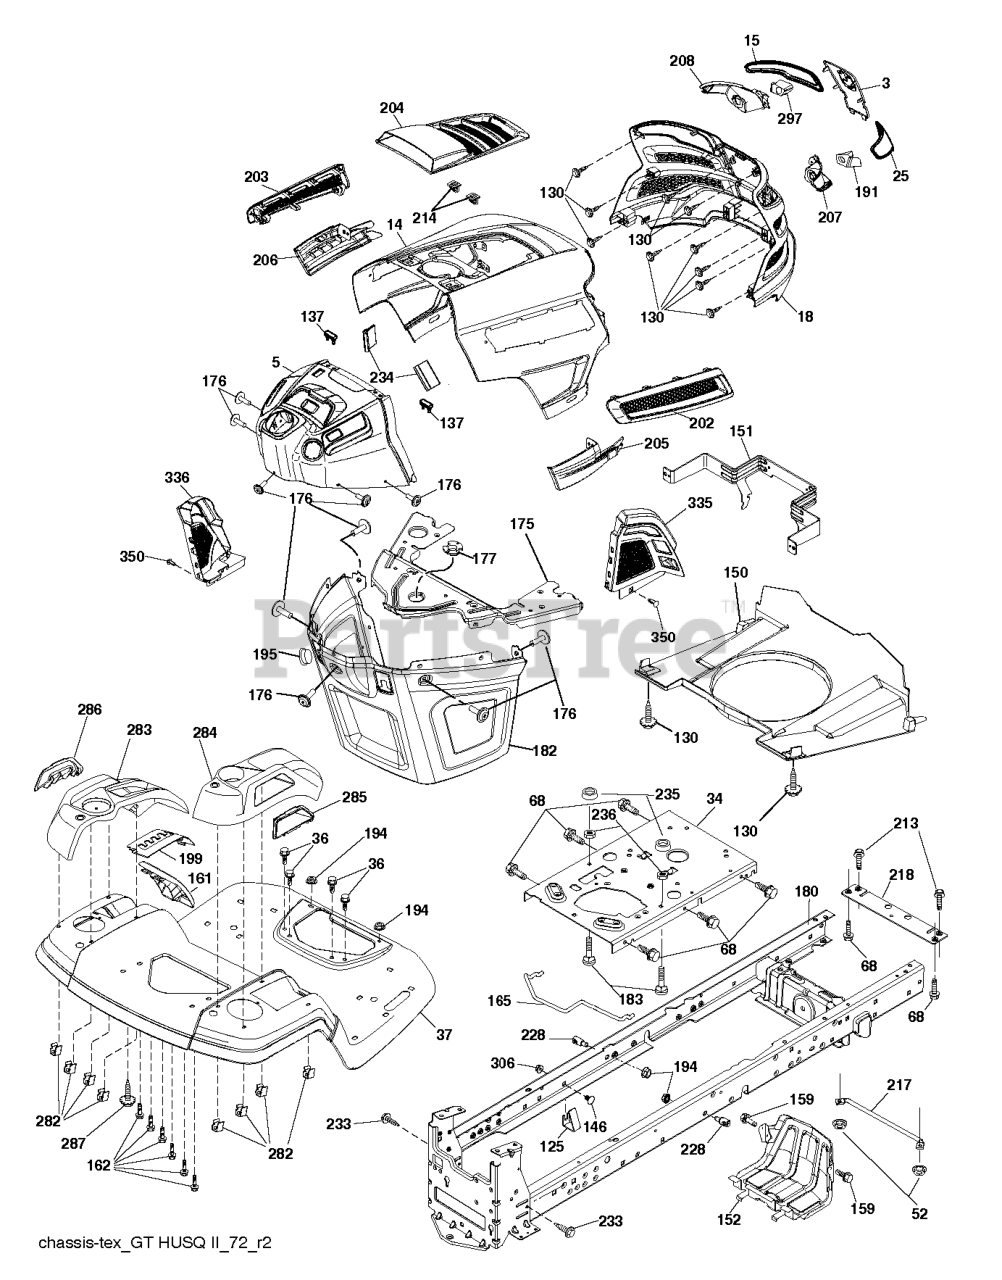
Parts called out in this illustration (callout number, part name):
3	APPLIQUE.SUBASM.GT.HUSQ.II
5	DASH.UPP.GT2.SM.PTO.MCHOKE
14	HOOD.ASM.HUSQVARNA.GT.TEX.ORAN
15	LENS.HEADLIGHT.LH.GTII.2011
18	GRILLE.SUBSTRATE.2011.
25	LENS.HEADLIGHT.RH.GTII.2011
34	PLATE.ENGINE.WELDED.CHASSIS
36	SCREW 5/16"
37	FENDER.TLT.FS.W/CPH/FW/RSF.668
52	LOCKNUT
68	Screw 5/16-18 x 1/2 Hex, Self Tapping 5/16-18 x 1/2
125	CLIP.FUEL.LINE
130	SCREW.#10 X 0.750.BOS
137	BUMPER DASH
146	BOLT.RDHD.SHT.SQNK.3/8-16X5/8
150	AIR.DUCT.GTV.BLACK
151	BRACKET.PIVOT.HOOD.GT.HUSQ.II
152	SHIELD.BROWNING.PNT.GT.V2
159	SCREW, 3/8-16X3/4
161	WINDOW.FUEL.LT.HUSQ.TEX.498
162	SCREW.HI-LO.CONSOLE
165	SUPPORT.TANK.REAR.W/TEX
175	PLATE.CROSSMEMBER.HUSQ
176	SCREW.#10-24X5/8.RN.QU
177	BUSHING, STEERING
180	CHASSIS
182	DASH.LOWER.COMMON.12V.ADAPTOR
183	BOLT.5/16-18X1-1/4 FULL THD
191	INSERT.REFLECTIVE.RH.HUSQ.GTII
194	NUT LOCK HEX FLANGE 5/16-18
195	PLUG.HOLE.DASH.LOWER.12V.BLK
199	PLATE.DECK.LIFT.HUSQ.LT
202	VENT.SIDE.RH.GT.HUSQ.II.
203	VENT.SIDE.LH.GT.HUSQ.II.498
204	VENT.TOP.ASM.HUSQ.GT2
205	SIDE.TRIM.RH.GT.HUSQ.II
206	SIDE.TRIM.LH.GT.HUSQ.II.GRAY
207	BEZEL LIGHT.RH.GT.II.MYLAR
208	BEZEL LIGHT.LH.GT.II.MYLAR
213	BOLT
214	CLIP.RETAINER.TINNER.
217	ROD.PIVOT.HOOD
218	X-PIECE.HOOD.STOP.NON/
228	STUD.FASTNER.W/ANTI-ROTATE
233	BOLT.SHOULDER
234	BUMPER.HOOD.TEX.HUSQVARNA
235	SPACER FENDER
236	NUT.CENTERLOCK.5/16-
282	CLIP.RETAINER.CONSOLE.LT.HUSQ
283	CONSOLE.DECK.LIFT.R.SDFL.HUSQ
284	CONCOLE.CNTRL.PDL.HUSQ.LT.498
285	CONSOLE INSERT RH
286	CONSOLE.INSRT.LH.HUSQ.LT.BLACK
287	SCREW 1/4X20
297	INSERT.REFLECTIVE.LH.HUSQ.GTII
306	NUT LOCK FLG 3/8-16 UNC
335	COVER.LOWER.DASH.RH.BLACK
336	COVER-LH.LOWER.DASH.GT2.BLACK
350	CLIP.X-MAS.TREE
